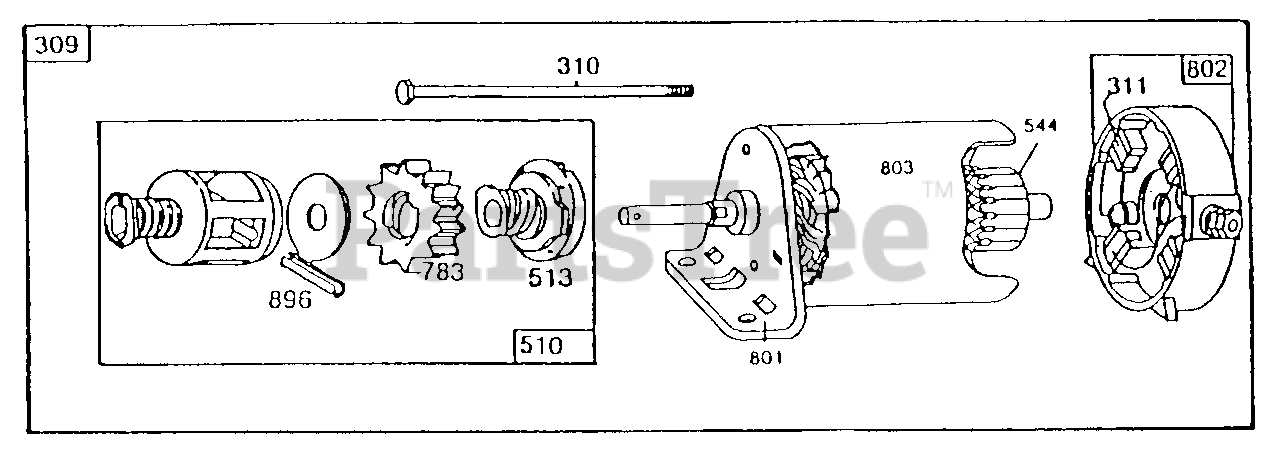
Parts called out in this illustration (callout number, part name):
309	Motor and Drive Ass'y
310	Thru Bolt Ass'y
311	Brush Ass'y
510	Drive Ass'y
544	Armature Ass'y
801	Drive End Cap Ass'y
802	End Cap Ass'y
803	Housing Ass'y
